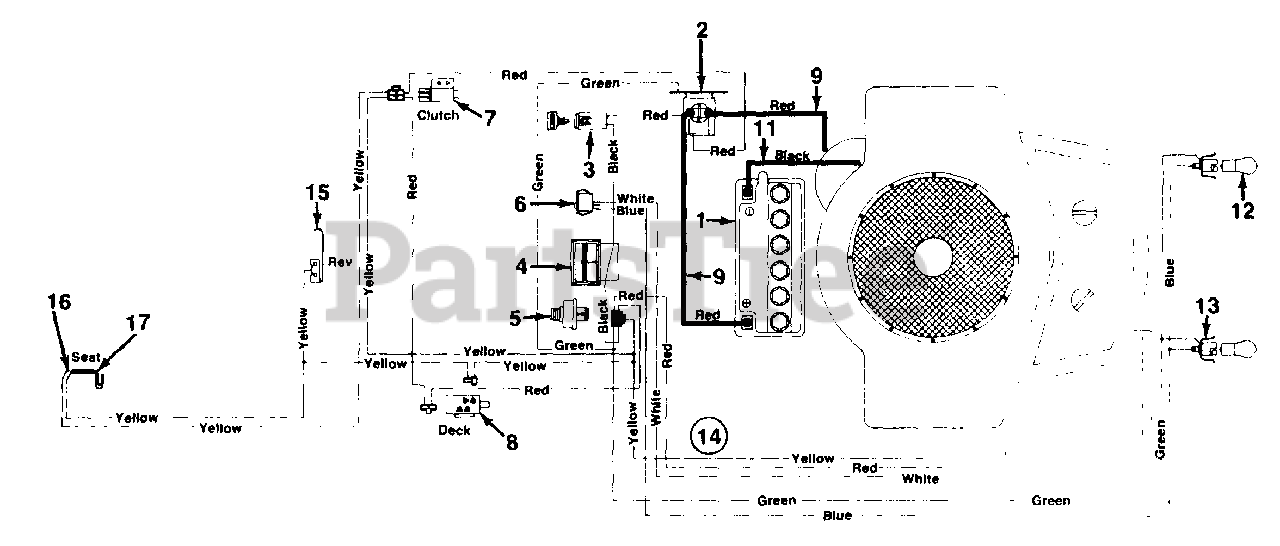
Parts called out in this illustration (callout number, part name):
1	Battery (275 Cold Crank Amps)
2	Solenoid
3	Fuse 7.5 Amp
4	Ammeter
5	Ignition Switch
6	Light Switch
7	Safety Switch (Clutch)
8	Safety Switch (PTO)
9	Electric Wire 14" Lg.
11	Ground Wire 7.5" Lg.
12	Lamp
13	Socket
14	Wire Harness
15	Spring Switch (Reverse)
16	Spring Switch (Seat)
17	Spring Switch (Seat)
